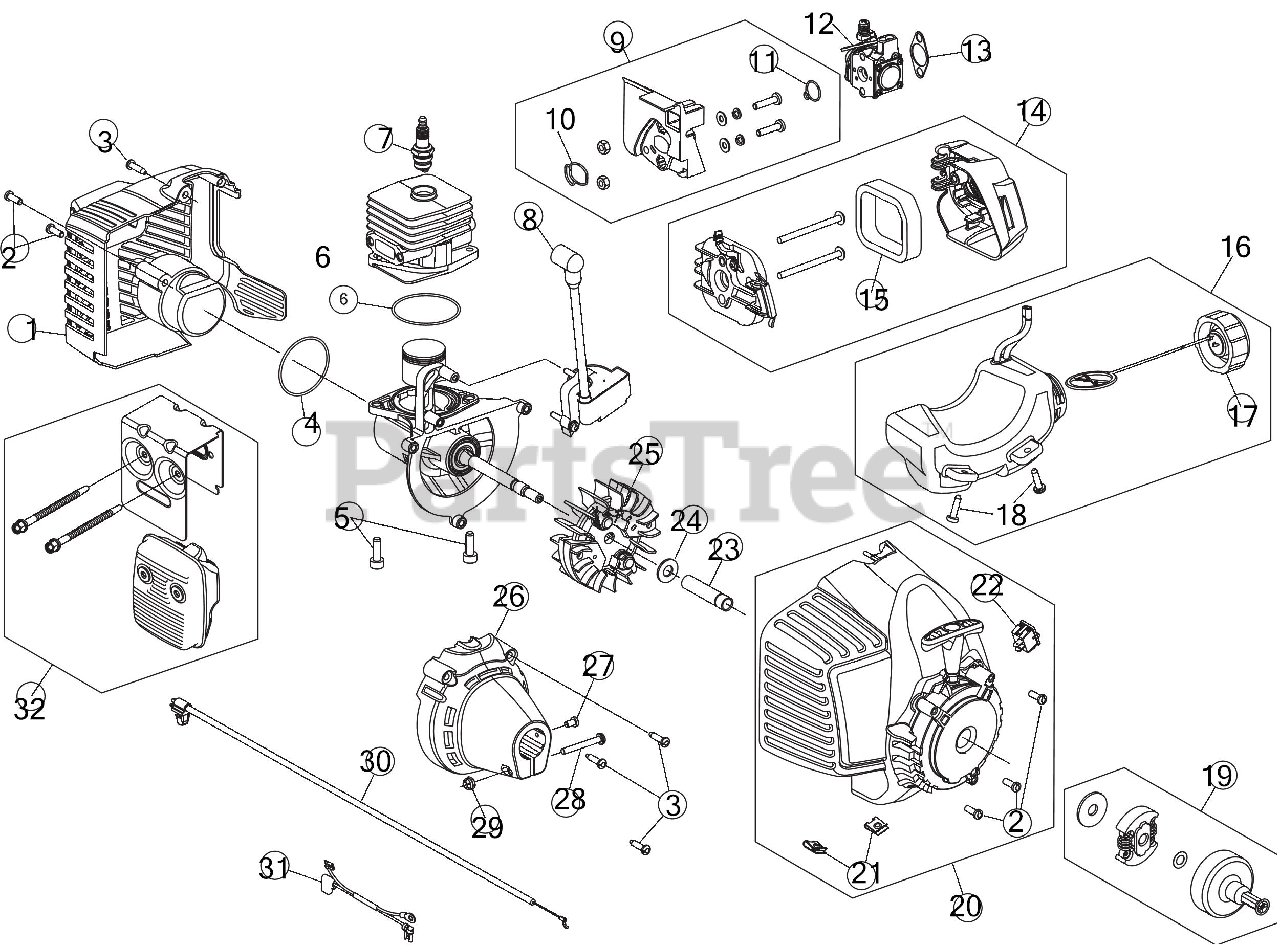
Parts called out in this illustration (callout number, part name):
1	ENGINE COVER RR
2	SCREW:10-32X.562:#8P
3	SCREW, #8-16X.750 PH
4	O-RING
5	SCREW, 1/4-20 x .75
6	O-RING
7	SPARK PLUG
8	MODULE ASSEMBLY RFI
9	INTAKE ASSEMBLY
10	O-RING
11	O-RING
12	CARB ASSEMBLY
13	GASKET CARB
14	AIRCLEANER COVER ASSEMBLY
15	AIR FLITER
16	FUEL TANK ASSEMBLY
17	FUEL CAP ASSEMBLY
18	SCREW 10-6 x .75
19	SMALL CLUTCH ASSEMBLY W/SMALL DRUM
20	STARTER HOUSING ASSEMBLY
21	NUT, TINNERMAN U-T
22	SW, MOMENTARY ON/O
23	SPACER
24	BELL WASHER
25	FLYWHEEL ASSEMBLY
26	CLUTCH COVER
27	SCREW, 8-32 x .312 P
28	SCREW
29	HEX NUT
30	THROTTLE CABLE
31	LEAD WIRES
32	MUFFLER ASSEMBLY
